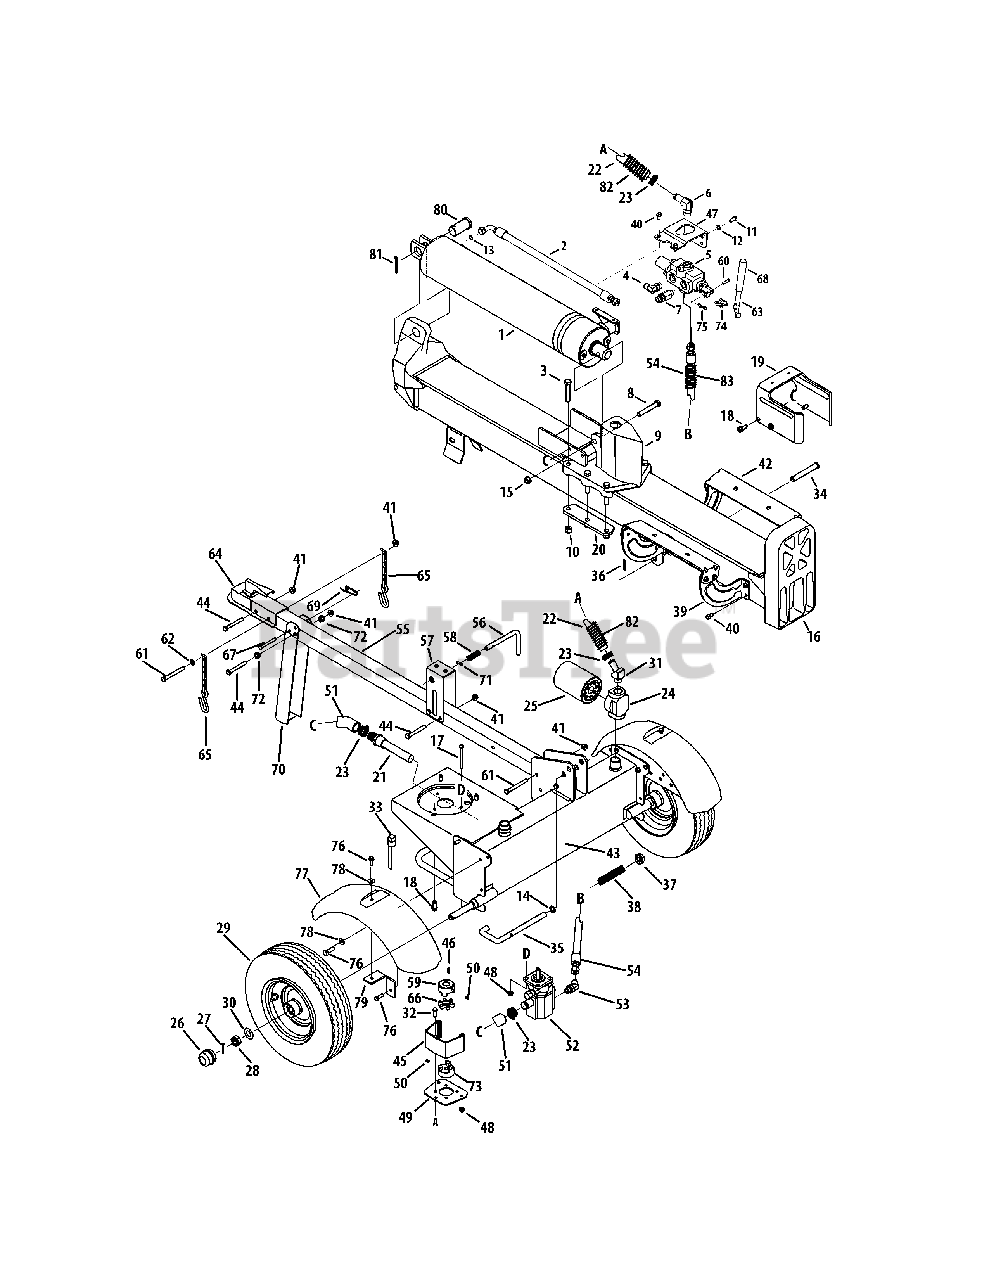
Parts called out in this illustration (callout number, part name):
1	Hydraulic Cylinder
2	Hydraulic Tube
3	Hex Cap Screw, 1/2-20 x 2.75
4	90 Degree Solid Adapter
5	Control Valve
6	Return Elbow
7	Nipple Pipe, 1/2-14
8	Hex Cap Screw, 1/2-13 x 3.25
9	Wedge Assembly
10	Hex Lock Nut, 1/2-20
11	Hex Cap Screw, 3/8-16 x .75
12	Lock Washer, 3/8
13	O-Ring, .489 ID x .070 Dia.
14	Flat Washer, .635 x.93 x.06
15	Hex Lock Nut, 1/2-13
16	Beam Assembly
17	Hex Screw, 5/16-18 x 3.25
18	Self Tapping Screw, 3/8-16 x 1.0
19	Dislodger Bracket
21	Inlet Filter
22	Return Hose, 3/4 x 44
23	Hose Clamp, 5/8
24	Filter Housing
25	Oil Filter
27	Cotter Pin
28	Slotted Nut, 3/4-16
29	Complete Wheel Assembly
29	Dust Seal
29	Roller Bearing
30	Flat Washer, .760 x.500
31	Hydraulic Fitting, 1 1/16 Orb x .75
32	Hex Screw, 5/16-18 x 1.00
33	Vented Dipstick
34	Clevis Pin
36	Cotter Pin
38	Compression Spring
39	Log Tray Bracket
40	Hex Washer Screw, 5/16-18 x .750
41	Flange Lock Nut, 3/8-16
43	Frame Assembly
44	Hex Bolt, 3/8-16 x 3
45	Coupling Shield
46	Square Key, 3/16" x .75
47	Outer Valve Bracket
48	Flange Lock Nut, 5/16-18
49	Rear Coupling Support Bracket
50	Set Screws
51	Hose
53	45 Degree Elbow Fitting
54	High Pressure Hydraulic Hose
55	Tongue Assembly
56	Latch Rod
58	Compression Spring
59	Coupling, .875
60	Clevis Pin
61	Hex Cap Screw, 3/8-16 x 3.50
62	Flat Washer, .375 x.738 x.063
63	Hydraulic Valve Control
64	Hitch Coupling Assembly
66	Spider Bushing
67	Clevis Pin
69	Spring Pin
71	Spiral Pin
72	Plastic Bushing, .380 ID
73	Coupling, .500
74	Valve Handle Link
75	Cotter Pin, Bow Tie
76	Self-Tapping Screw, 5/16-18 x 1.00
78	Flat Washer
79	Fender Mounting Bracket
80	Clevis Pin, 1.25 x 2.50
81	Cotter Pin, 3/16 x 2
82	Hose Guard, 48"
83	Hose Guard, 44"
